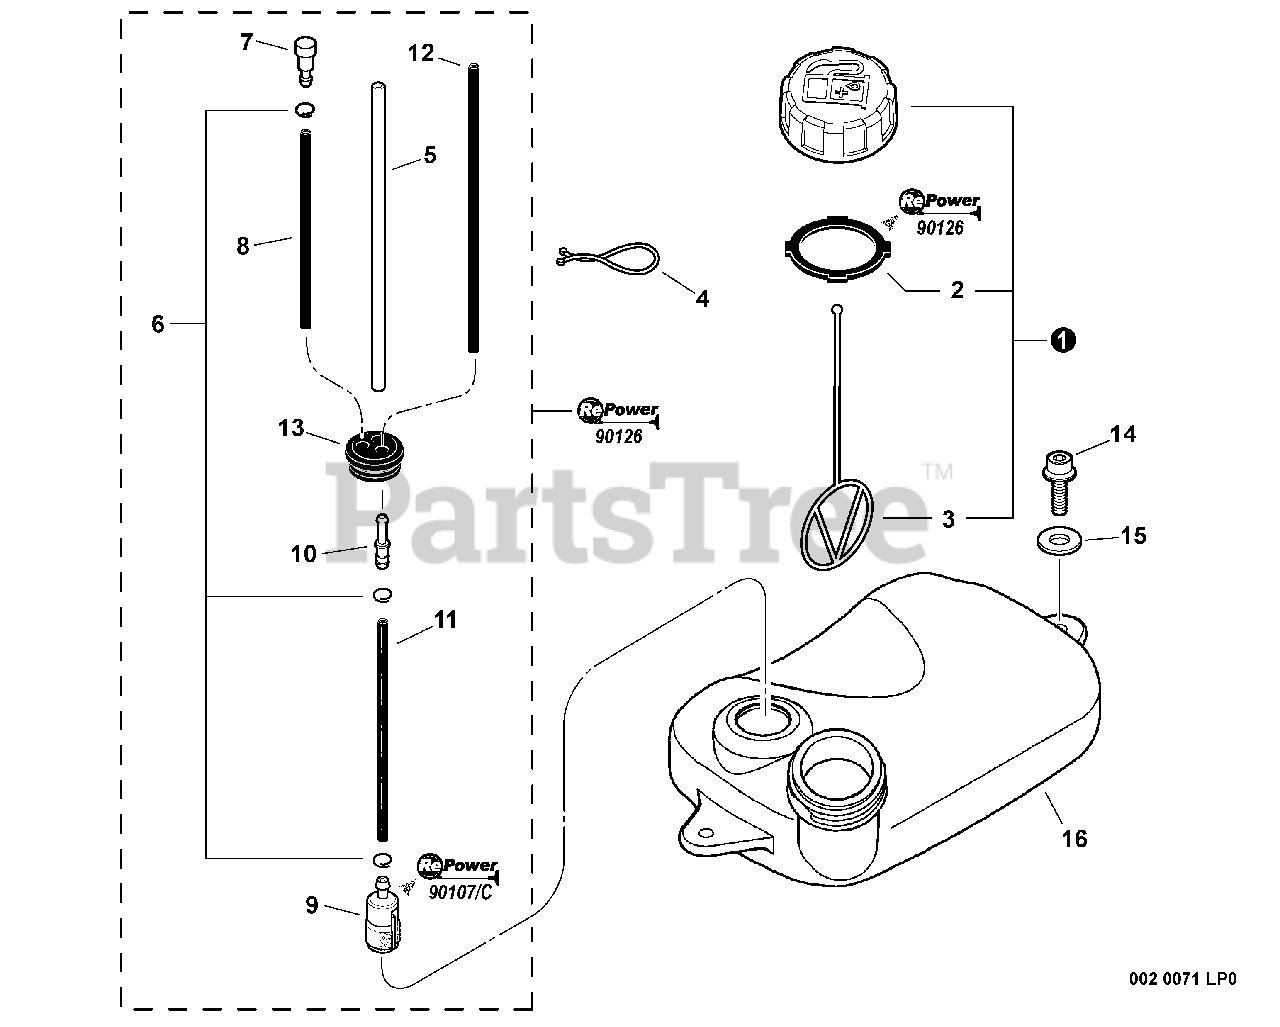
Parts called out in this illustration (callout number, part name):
1	CAP ASSY - ORANGE
2	GASKET, CAP
3	CONNECTOR, CAP
5	PIPE - 3X6X125 -- CLEAR
6	CLIP - 6
7	VENT, FUEL TANK
8	PIPE - 3X5X70 -- BLACK
9	FILTER, FUEL
10	CONNECTOR, PIPE
11	PIPE - 3X5X90 -- BLACK
12	PIPE - 3X5X120 -- BLACK
13	GROMMET
14	SCREW - 5X20
15	WASHER - 5
16	TANK, FUEL
17	RePower FUEL SYSTEM KIT
18	RePower TUNE-UP KIT
